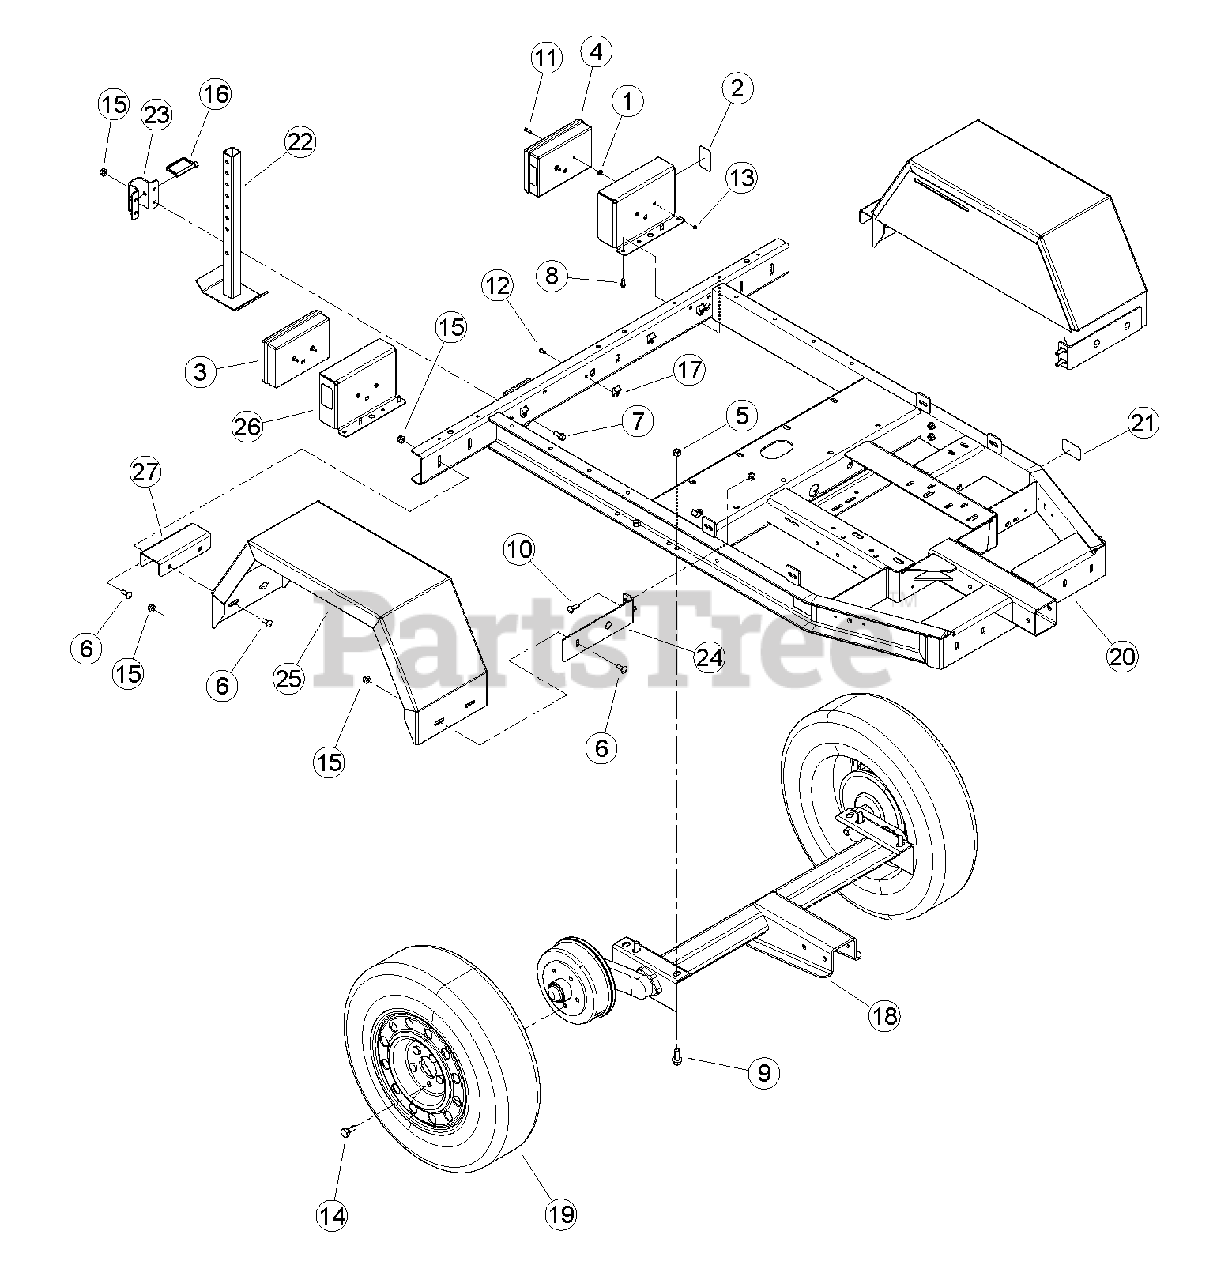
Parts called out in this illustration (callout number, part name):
1	GROMMET, 1/4 X 5/8 RUBBER
2	REFLECTOR, WIDE ANGLE RED
3	LIGHT, TAIL RH
4	LIGHT, TAIL LH
5	NUT, 1/2" CENTERLOCK GRB ZP
6	BOLT, 3/8 X 1" GR5 CRG NC ZP
7	BOLT, 3/8 X 1 FLANGE NC
8	SCREW, 11/32 X 7/8 HWH AB THREAD ZP
9	BOLT, 1/2 -13 X 1-1/4 FLANGE NC
10	BOLT, 3/8 X 1-1/4" GR5 CRG NC ZP
11	BOLT, 10-24 X 3/4" HHCS GR8 PLAIN
12	RIVET, AL BLIND 1/4 X 3/4 DOME HEAD
13	NUT, #10-24 K-LOCK ZP
14	BOLT, 12MM LUG FOR WHEELS
15	NUT, 3/8-16 NYLOCK FLANGE
16	PIN, 3/8 X 2-3/4" SNAP
17	CLAMP, CABLE MOUNT
18	AXLE, TORSION W/ BRAKES
19	WHEEL/TIRE, P205/65R15
20	ASSEMBLY, CH611DHXE/XF TRAILER W/ DECALS VIN
21	REFLECTOR, WIDE ANGLE AMBER
22	WELDMENT, REAR STABILIZER
23	GUIDE, TRAILER SUPPORT
24	BRACKET, FENDER
25	WELDMENT, CHIPPER FENDER
26	BRACKET, TAIL LIGHT
27	PLATE, FENDER SPACER
